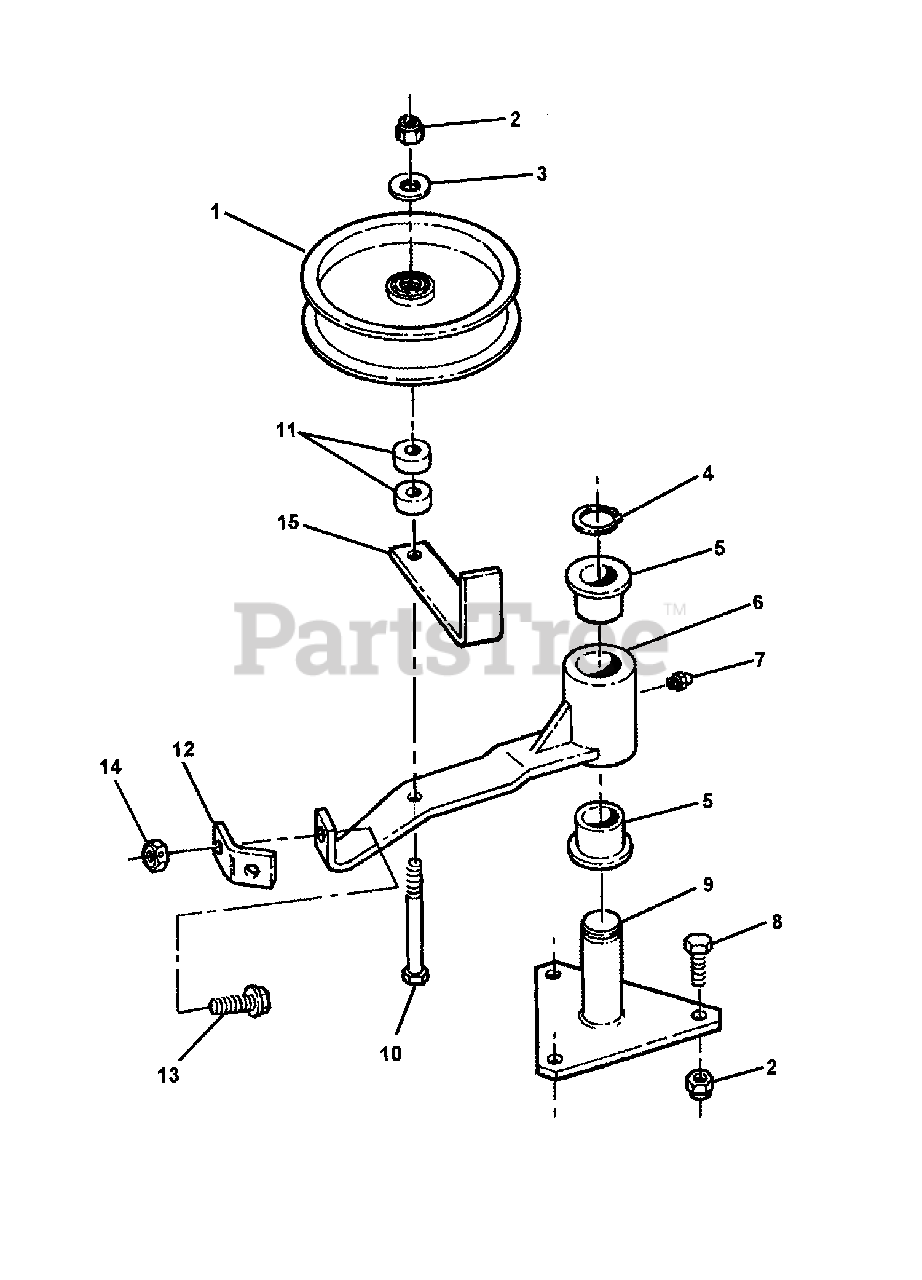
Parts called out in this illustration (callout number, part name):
1	PULLEY, Idler (5.00 O. D.)
2	NUT, 3/8-16 HEX NYLON LOCK
3	WASHER, 7/16" I.D. x 1" O.D.
4	RING, 1" External Retaining
5	BUSHING
6	IDLER ARM, 36" (Weldment)
7	FITTING, 1/4-28 Straight Lube
8	BOLT, 3/8-16 X 1" GD5 CZ
9	PIVOT, Idler Arm (Weldment)
10	SCREW, 3/8-16 x 3-1/4" Hex Head Cap, GR 5
11	SPACER
12	BRACKET, Idler (Pro 36)
13	BOLT, 3/8-16 x 1" Hex Flange Lock, GR 5
14	NUT, 3/8-16 Hex Center Lock, GR 5 or B
15	RETAINER, Belt - Idler
